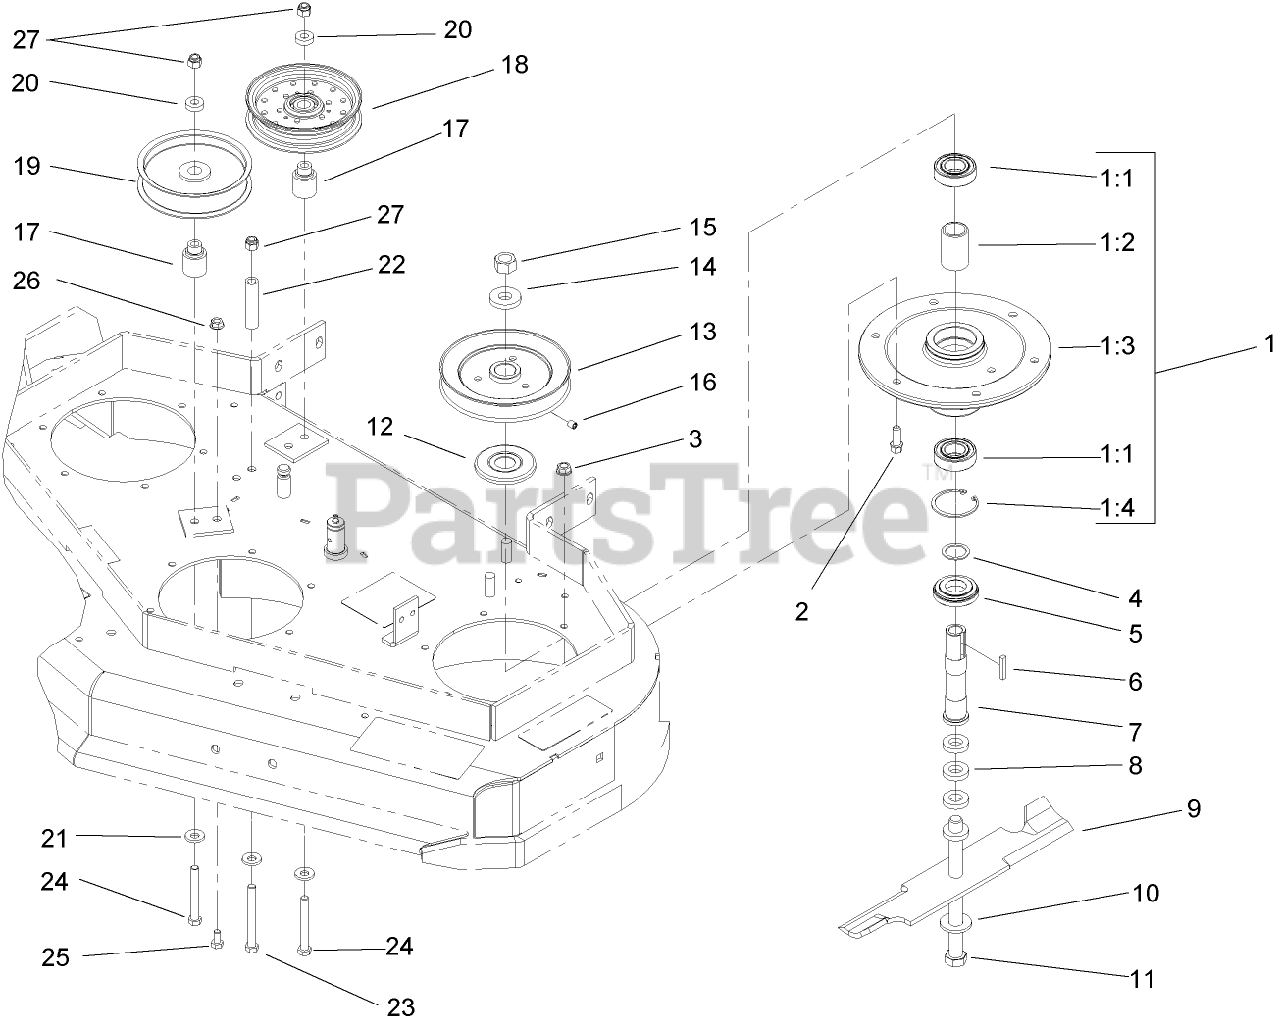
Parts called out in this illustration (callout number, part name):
1	SPINDLE HOUSING ASM
1:1	BEARING
1:2	SPACER-BEARING
1:3	HOUSING-SPINDLE
1:4	RING-SNAP
2	SCREW-HWH
3	NUT-HHF, WHIZ
4	WASHER-SPACER
5	SPACER-GUARD, BOTTOM
7	TUBE-SPINDLE, SHORT
8	SPACER
9	BLADE-14 INCH (HIGH SAIL)
10	WASHER-SPRING
11	SCREW-CAP, HH
12	Guard-Bearing, Top
13	SHEAVE
14	WASHER-RETAINER, SHEAVE
15	NUT-HEX
16	SCREW-SET
17	BUSHING-IDLER
18	IDLER-PULLEY, FLAT
19	PULLEY-IDLER
20	SPACER
21	WASHER-BELLEVILLE
22	SPACER
23	SCREW-HH
24	SCREW-HH
25	SCREW-HH
26	NUT-HF
27	NUT-LOCK, NI
